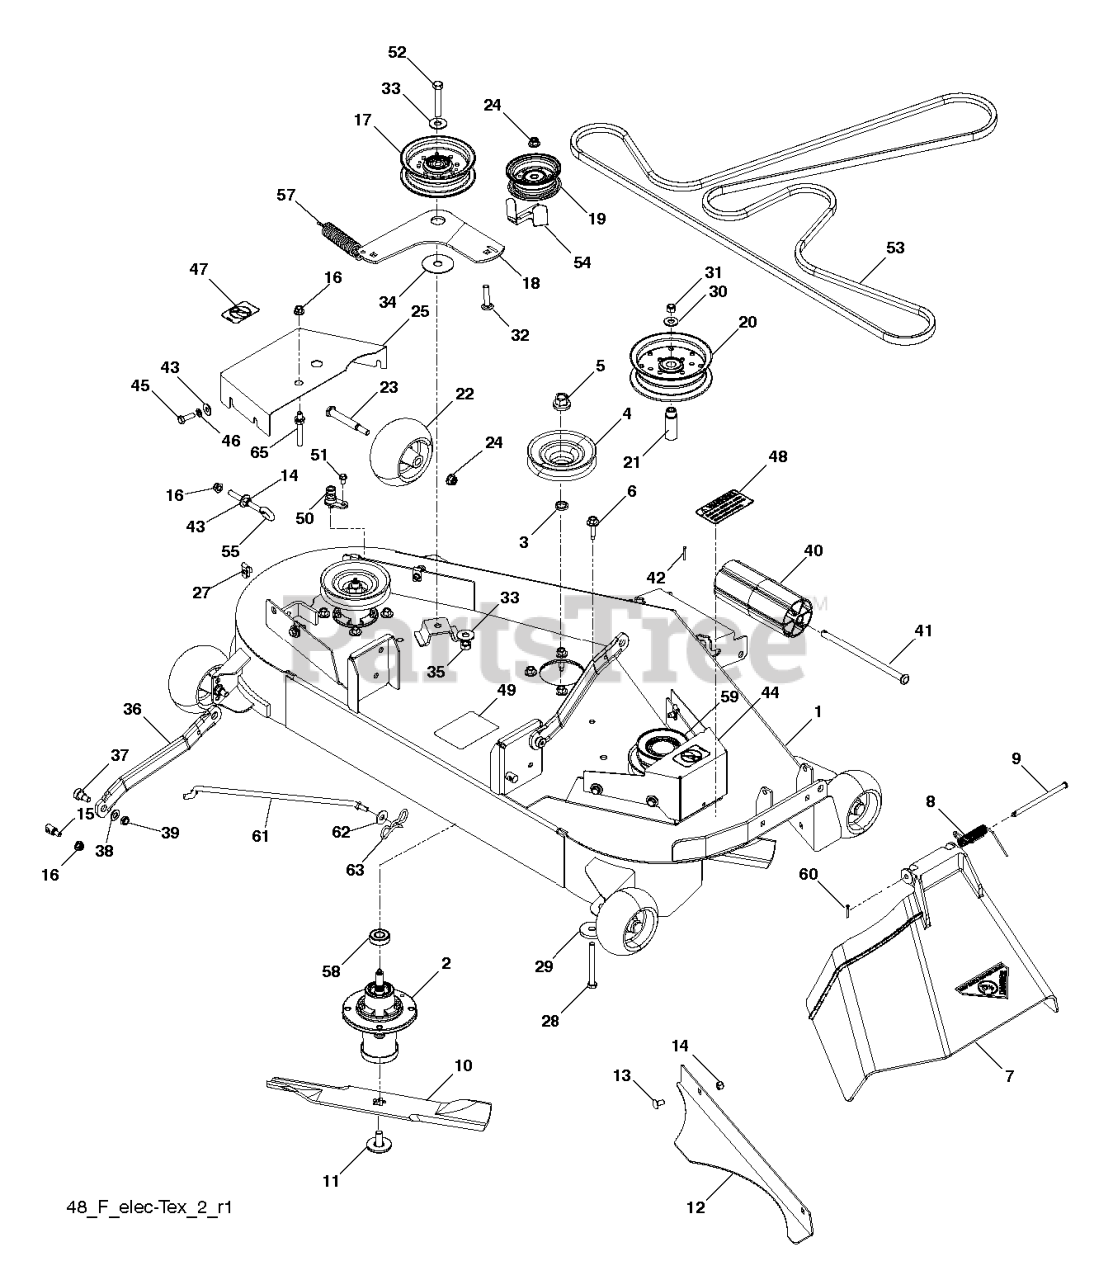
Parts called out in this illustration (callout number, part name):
1	Decks
2	MANDREL.DECK.ASSEMBLY
3	WASHER.SPACER.MANDREL
4	PULLEY.DRIVEN.DECK.48'
5	NUT.FLANGE.LOCK.TOP
6	SCREW, WASHER HEAD
7	DISCHARGE CHUTE 48"
8	SPRING - TORSION
9	PIN-CLEVIS 5/16 DIA X 5.19 ZD
10	BLADE, 16-1/4"
11	BOLT.WASHER.ASM.7/16-2
12	PLATE.CONFINEMENT.48"
13	BOLT.CARR.5/16-18X5/8.SHORT
14	NUT.71038.31-18.HEX.NYLOCK
15	STUD.FASTNER.W/ANTI-ROTATE
16	5/16-18 NYLOC FLANGE NUT
17	PULLEY.IDLER.MWR.STATI.LH
18	ARM IDLER RAW
19	PULLEY.IDLER.FLAT
20	PULLEY, IDLER
21	BUSHING, IDLER
22	GAUGE WHEEL
23	BOLT.SHOULDER.3/8-16X3-5/8.
24	NUT 3/8-16 HEX FLG NYLOC ZD
25	SHIELD.BELT.LH.ORANGE
27	U-CLIP 5/16-18 NUT RETAINER
28	HCS 3/8-16 X 3-1/2 GR5 ZD
29	SPINDLE WASHER
30	RP WASHER 3/8 FLAT
31	NUT 3/8-16 NYLOC
32	RHSNB 3/8-16X1-3/4
33	WASHER 7/16 FLAT ZD
35	NUT 7/16-14 HEX WHIZ LK SMOOTH
36	ARM.SUSPENSION.MOWER
37	SB 3/8-16 X 3/8 SKT HD ZD
38	WASHER
39	NUT HEX 3/8-16 NYLON, THIN
40	NOSE ROLLER 48"
41	ROD.ROLLER.NOSE.NARROW.48"
42	PIN.COTTER.5/16.BOW TI
43	WASHER.5/16.FLAT.STE.STD.
44	SHIELD, BELT, RH 48 ORG
45	BOLT.FIN.HEX.5/16-18UNC X 1.00
46	WASH.5/16.SLW.ZD
47	DECAL, NO STEP
48	DECAL, CAUTION
49	DECAL.MOWER.SCH.48/54
50	PORT.WASHOUT
51	SCREW
52	BOLT.HEX.7/16-14
53	BELT, 135" EL
54	GUARD, BELT
55	EYE BOLT 5/16 X 3.50
58	BEARING, BALL
59	RP PULLEY, COLLECTION 48
60	RETAINER CLIP
61	ROD.ANTI.SWAY.48/54"K4
62	WASHER
63	PIN.COTTER.5/16.BOW TI
65	KEEPER.BELT.ENGINE
